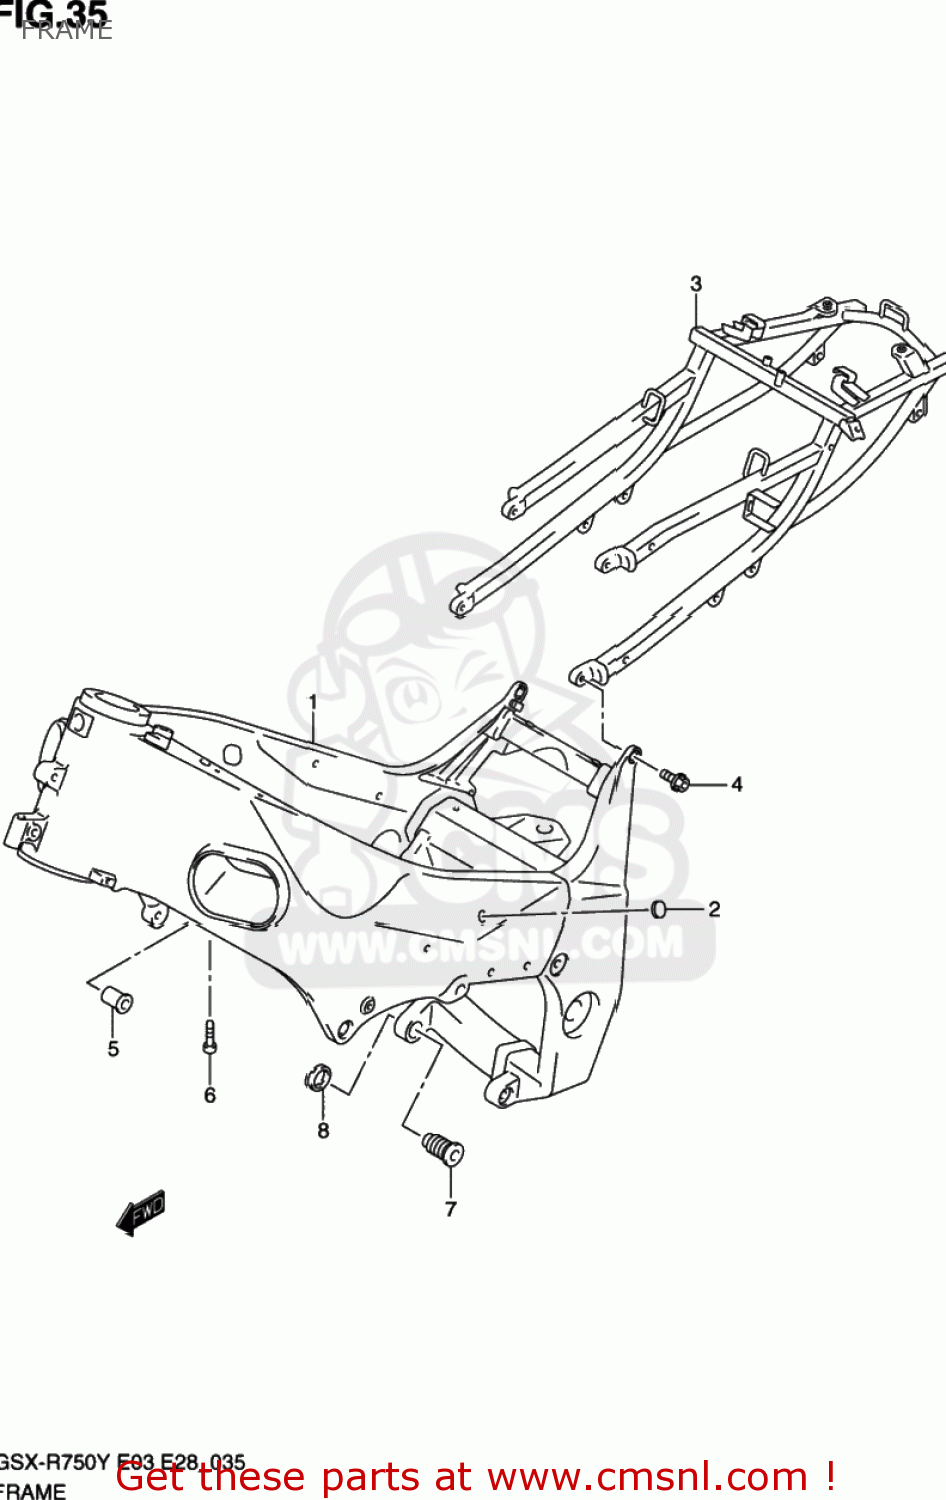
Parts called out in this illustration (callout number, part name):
1	FRAME
2	CAP,TANK RAIL
3	RAIL COMP,SEAT
4	BOLT,SEAT RAIL
5	SPACER,ENGINE MOUNTING
6	BOLT
7	BOLT,CRANK CASE ADJUST
8	NUT,CRANK CASE ADJUST BOLT
